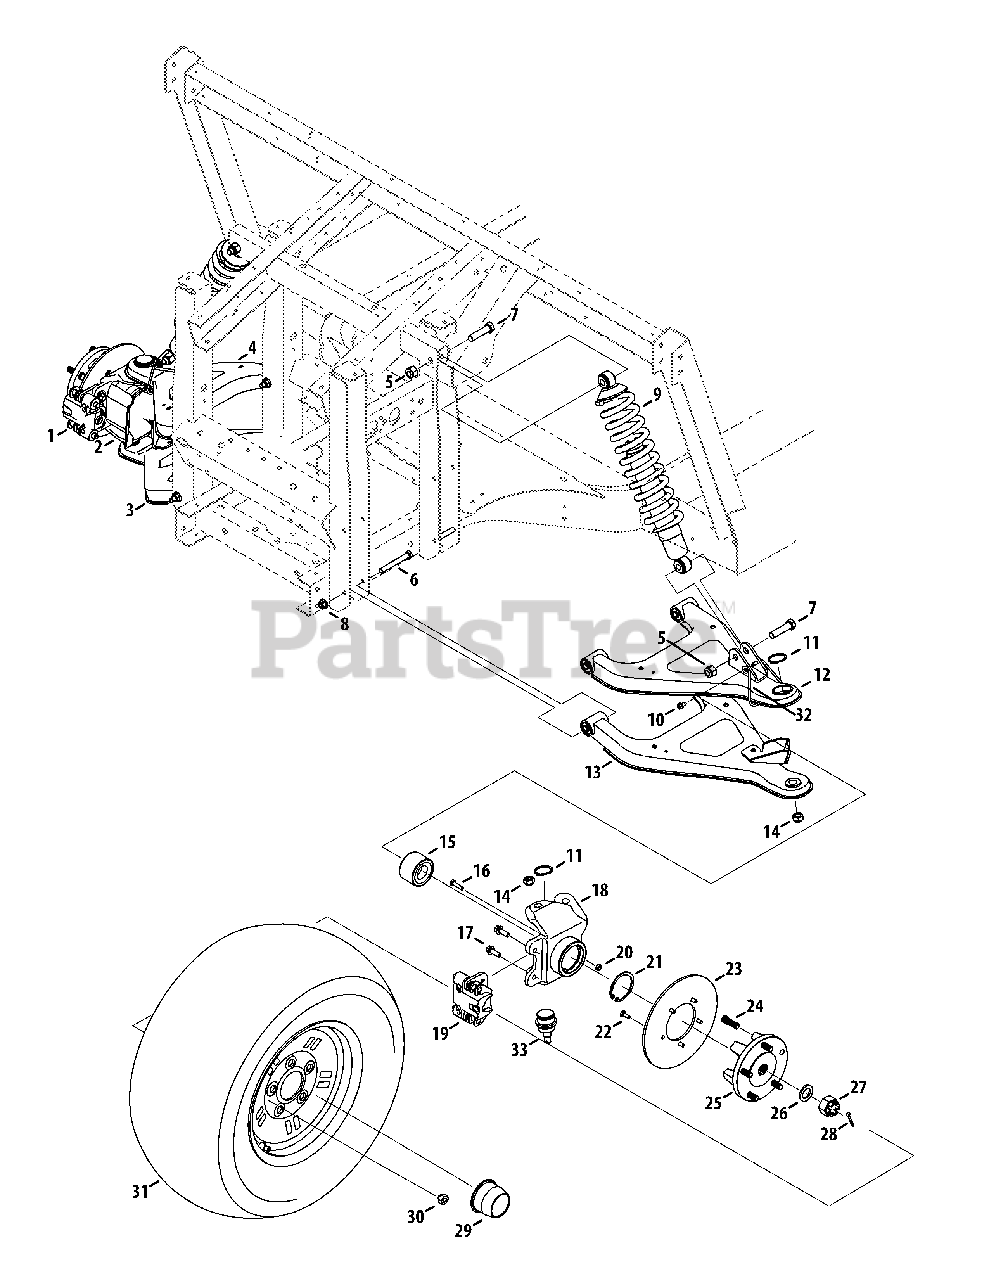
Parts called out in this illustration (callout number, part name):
1	Brake, hyd, caliper, frt, RH
2	Housing, knuckle, r/frt, mach
3	Control Assembly, r/frt, lwr
4	Arm Assembly, r/frt, upr
5	Nut, Hex Lock, 1/2-13, Nylon
6	Screw, 3/8-16, 3.00, gr8, std
7	Screw, 1/2-13, 2.00, gr5, std
8	Nut, Flange Lock, 3/8-16, Nylon
9	Shabs, 5.0 Stroke, frt
10	Screw, tt, 1/4-20x.500
11	Ring, Retainer, 34 x 1.6
12	Control Assembly, l/frt, upr
13	Control Assembly, l/ftr, lwr
14	Nut, Nylock, m12 x 1.25
15	Bearing, double Row, 60x30x37
16	Screw, 1/4-20 x 1.00,
17	Screw, m8-1.25, 25.00
18	Housing, knuckle, l/frt, mach
19	Brake, hydraulic, caliper, frt, LH
20	Nut, Hex,1/4-20
21	Ring, Retainer, dho-60
22	Screw, 1/4-20, .625, gr5, lock
23	Disc, brake, 8.00x.188
24	Stud, rib Neck, 7/16-14 x 1.6
25	Hub, wheel
26	Washer, flat, .88 x 1.38 x .125, ht
27	Nut, slotted, 22x1.5
28	Pin, cotter, 5/32, 1.25
29	Cap, Wheel UV
30	Nut, lug, 7/16-14
31	Wheel Assembly, 25 x 10-12
31	Tire Only, 25 x 10.5-12
32	Wire, Brake Line
33	Ball Joint, 14d-6201
